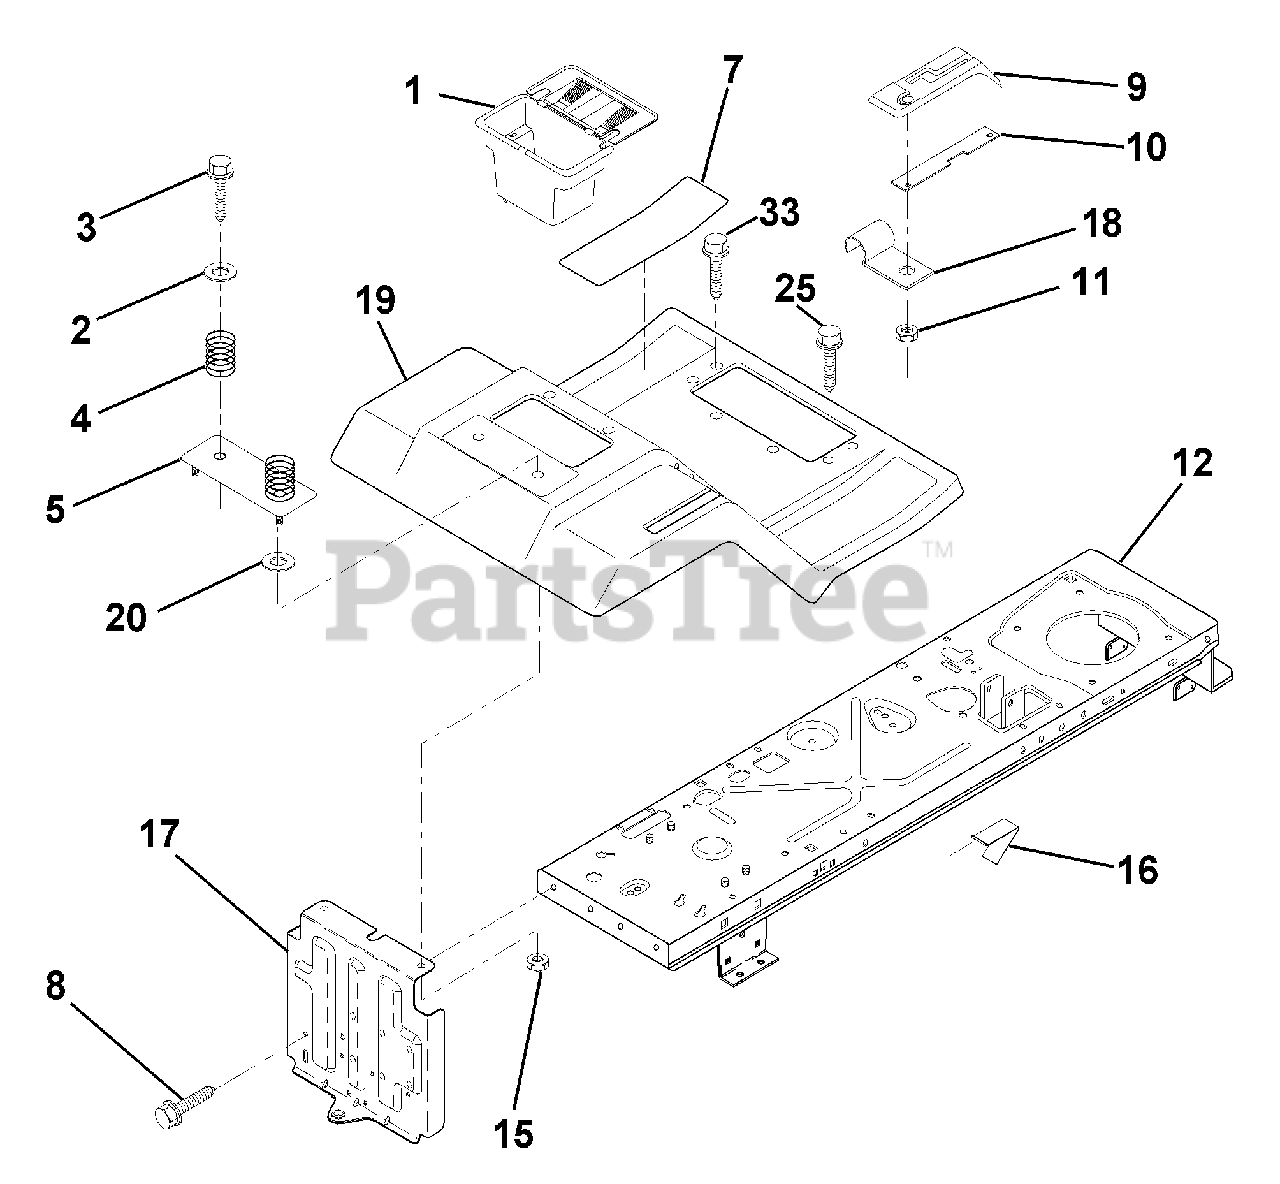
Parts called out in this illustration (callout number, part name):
1	Case, Battery
2	Washer 13/32 x 1-1/4 x 12 Ga.
3	Screw, Hex Wsh. Thrdrol. 3/8-16 x 3/4
4	Spring, Compression, Seat
5	Plate, Asm. Battery
7	Pad, Footrest
8	Screw, Hex Wsh Thdrol. 5/16-18 x 3/4
9	Console, Shift Control
10	Bar, Shift Lock
11	Nut, Self-Thrd., Wsh. Head 3/16
12	Assembly, Frame
15	Nut, Keps Hex 1/4-20 UNC
16	Switch Actuato
18	Clip, Insulated
19	Fender/Footrest
20	Washer 9/32 x 7/8 x 13 Ga.
25	Screw Tapping 5/16-18
33	Screw Hex Wsh Thdroll 5/16-18 x 1
34	Bolt Shoulder 5/16-18 TT
